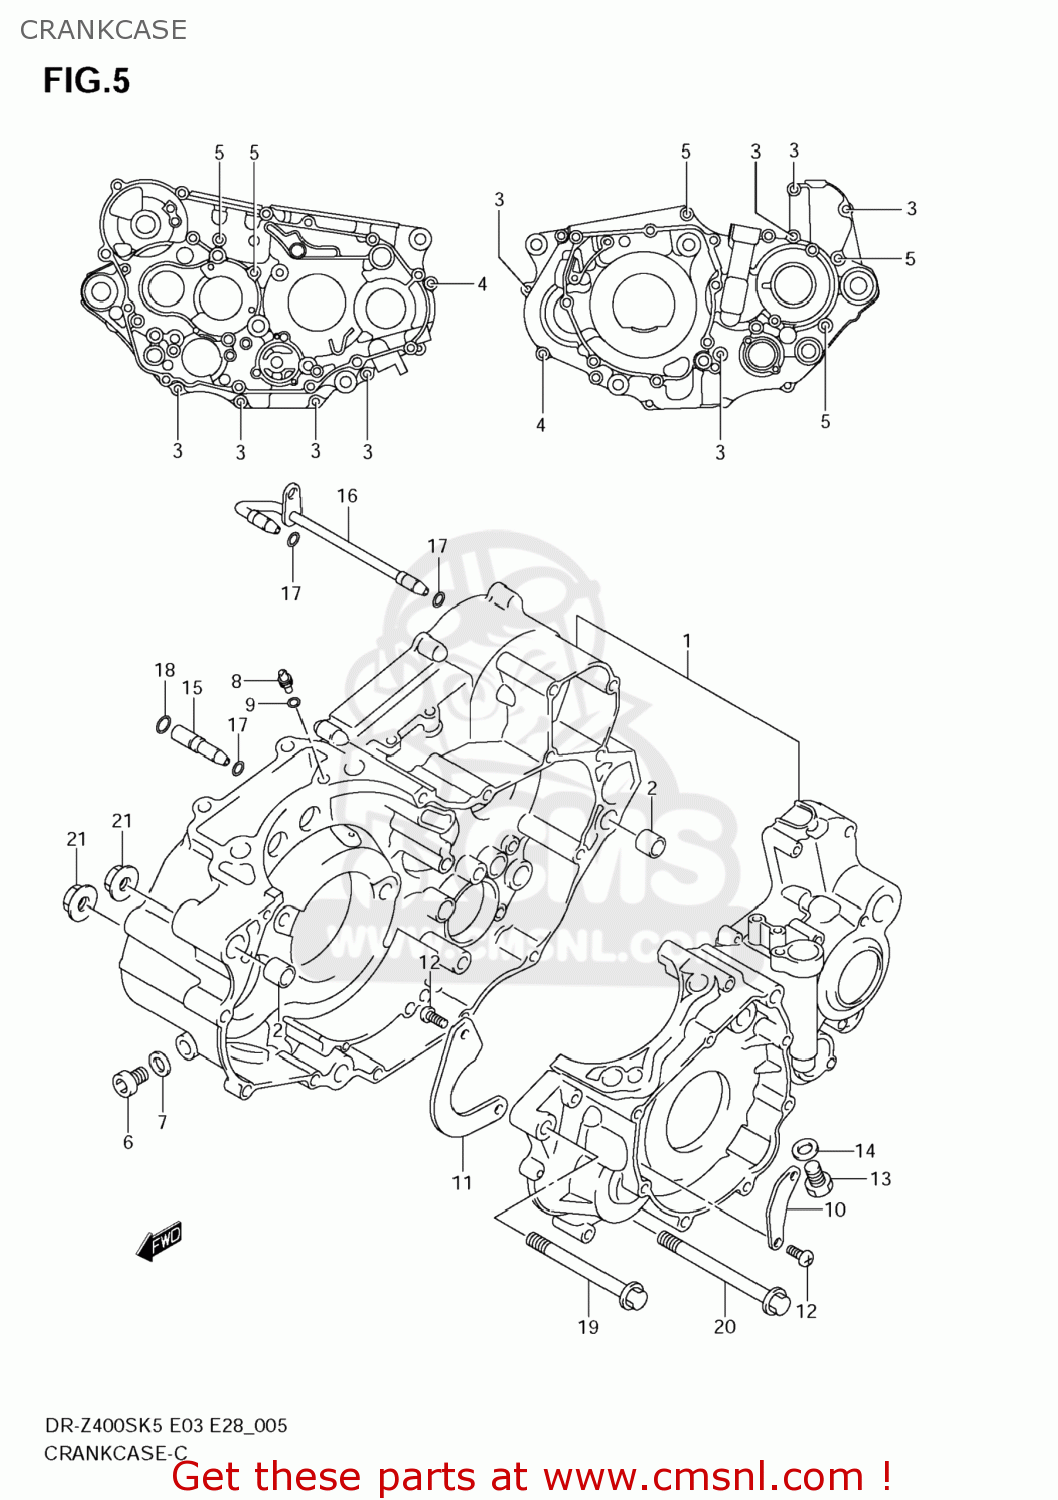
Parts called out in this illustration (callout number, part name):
1	CRANKCASE SET
2	PIN
3	BOLT
4	BOLT
5	BOLT
6	PLUG(10X10)
7	GASKET(10X14X3.6) (NAS)
8	JET(8)
9	O RING(D:1.2,ID:4)
10	SEPARATOR,CRANKCASE OIL NO.1
11	SEPARATOR,CRANKCASE OIL NO.2
12	BOLT(6X12)
13	PLUG(12X20)
14	GASKET(12.1X16.2X3.7) (NAS)
15	PIPE,OIL INNER NO.1
16	PIPE,T/M OIL INNER NO.2
17	O RING(D:1.9,ID:4.8)
18	O RING(D:1.9,ID:6.8)
19	BOLT(10X100)
20	BOLT(10X115)
21	NUT
